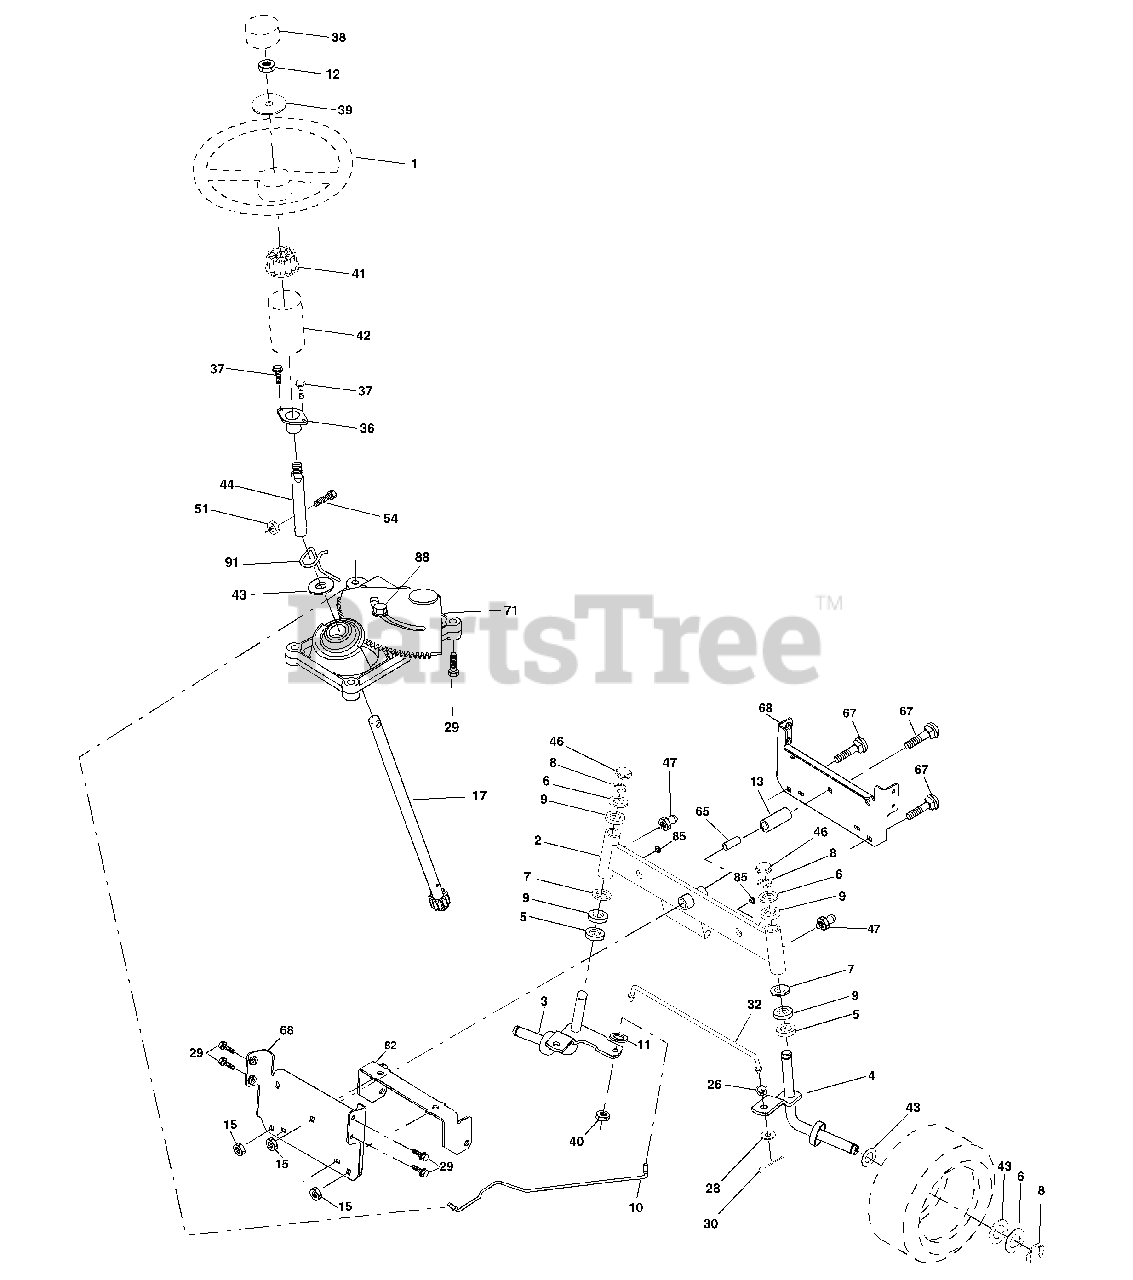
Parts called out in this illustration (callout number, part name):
1	Wheel Steering
2	Axle Asm
3	Spindle Asm LH
4	Spindle Asm RH
5	Bearing Race Thrust Harden
6	Washer 25/32 x 1-5/8 x 16 Ga
7	Washer 27/32 x 1-1/4 x 16 Ga
8	Ring Klip #t5304-75
9	Bearing Col Strg Blk
10	Link Drag
11	Washer Lock Hvy Hlcl Spr 3/8
12	Nut Hex Jam Toplock 1/2-20
13	Spacer earing Axle Front
15	Hexflange Lock
17	Shaft Asm Strg
26	Bushing Link Drag Blk LR
28	Washer 13/32 x 7/8 x 16 Ga
29	Screw 3/8-16 x 3/4
30	Pin Cotter 1/8 x 3/4 Cad
32	Rod Tie Wire Form 19 75 Mech
36	Bushing Strg 5/8 Id Dash
37	Screw
38	Cap Wheel Steer Ayp
39	Washer 9/16 x 2-3/8
40	Nut Lock Center 3/8-24un
41	Adaptor Wheel Strg
42	Boot Dash Mtl Steering Blk
43	Washer 25/32 X 1 1/4 X 16 Ga
44	Extension Steering
46	Cap Spindle Fr Top Blk
47	Fitting Grease
51	Nut 1/4-28
54	Bolt Hex 1/4-28 x 1-1/4
63	Bolt Fin Hex 3/8-16unc x 1 Gr.5
65	Spacer Brace Axle
67	Bolt Fin Hex 5/8-11 unc x 2-3/4
68	Brace Axle
71	Steering Asm.
82	Bracket Susp Chassis Front
85	Fastener Christmas Tree
88	Bolt Shoulder 7/16-20
91	Clip Steering
